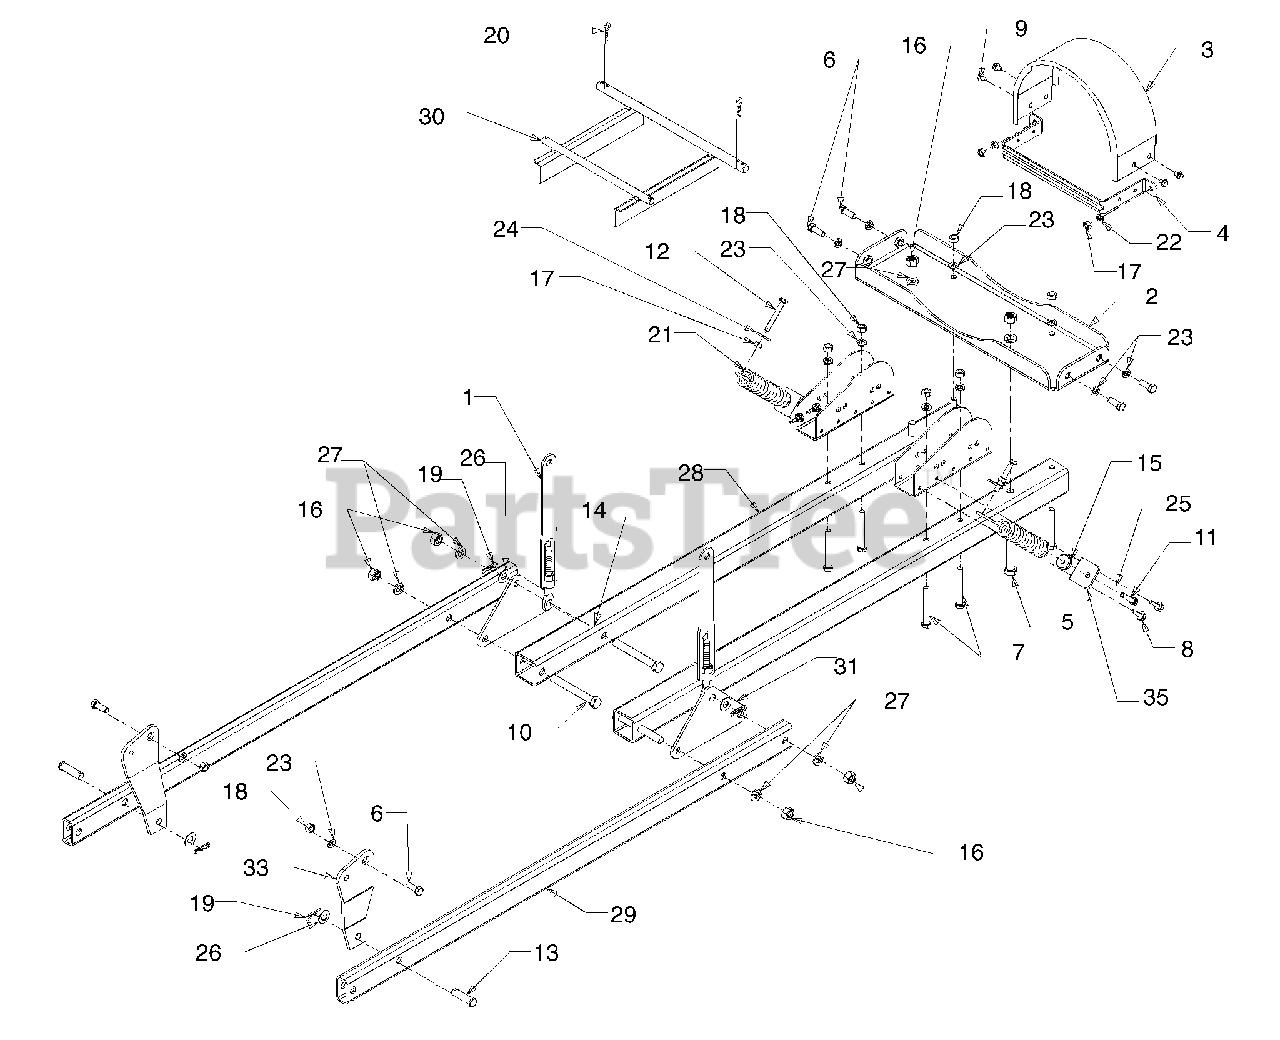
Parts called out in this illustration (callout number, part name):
1	LIFT ASM:DECK LINK:FRONT
6	HHCS:3/8-16:1.00:GR5:STD
7	HHCS:3/8-16:3.00:GR8:STD
8	HEX WASH SF TAPP SCR 5/16-18
9	SCR:TT:1/4-20:.375:HXINDWSH
10	HHCS:1/2-13:4.00:GR5:STD
11	HHCS:5/16-18:1.50:GR5:SPEC
12	HHCS:5/16-18: 2.50:GR5:STD
13	PIN:CLV:.50 DIA X 1.59 LG
14	PIN:CLV:.50 DIA X .78 LG
16	NUT:1/2-13:GRA:HX
17	NUT:5/16-18:GRB:HX
18	NUT:3/8-16:GRB:HX
19	PIN:COT:INT .08 X 1.42
20	PIN:COT:.125 X 1.75 INTERNAL
21	SPR:EXTN:1.25 OD X 7.25
22	WASH:LOCK:5/16:REGULAR DUTY
23	WASH:LOCK:3/8:REGULAR DUTY
24	WASH:FL: .344 ID X 1.125 OD
25	WASH:BELVL:.340 ID X .872 OD
26	WASH:FL:.510 X 1.00 X .060
27	WASH:LOCK:1/2:REGULAR DUTY
28	TUBE:LIFT:2.0 X 2.0 X 42.0
31	BRKT:LIFT PLATE
